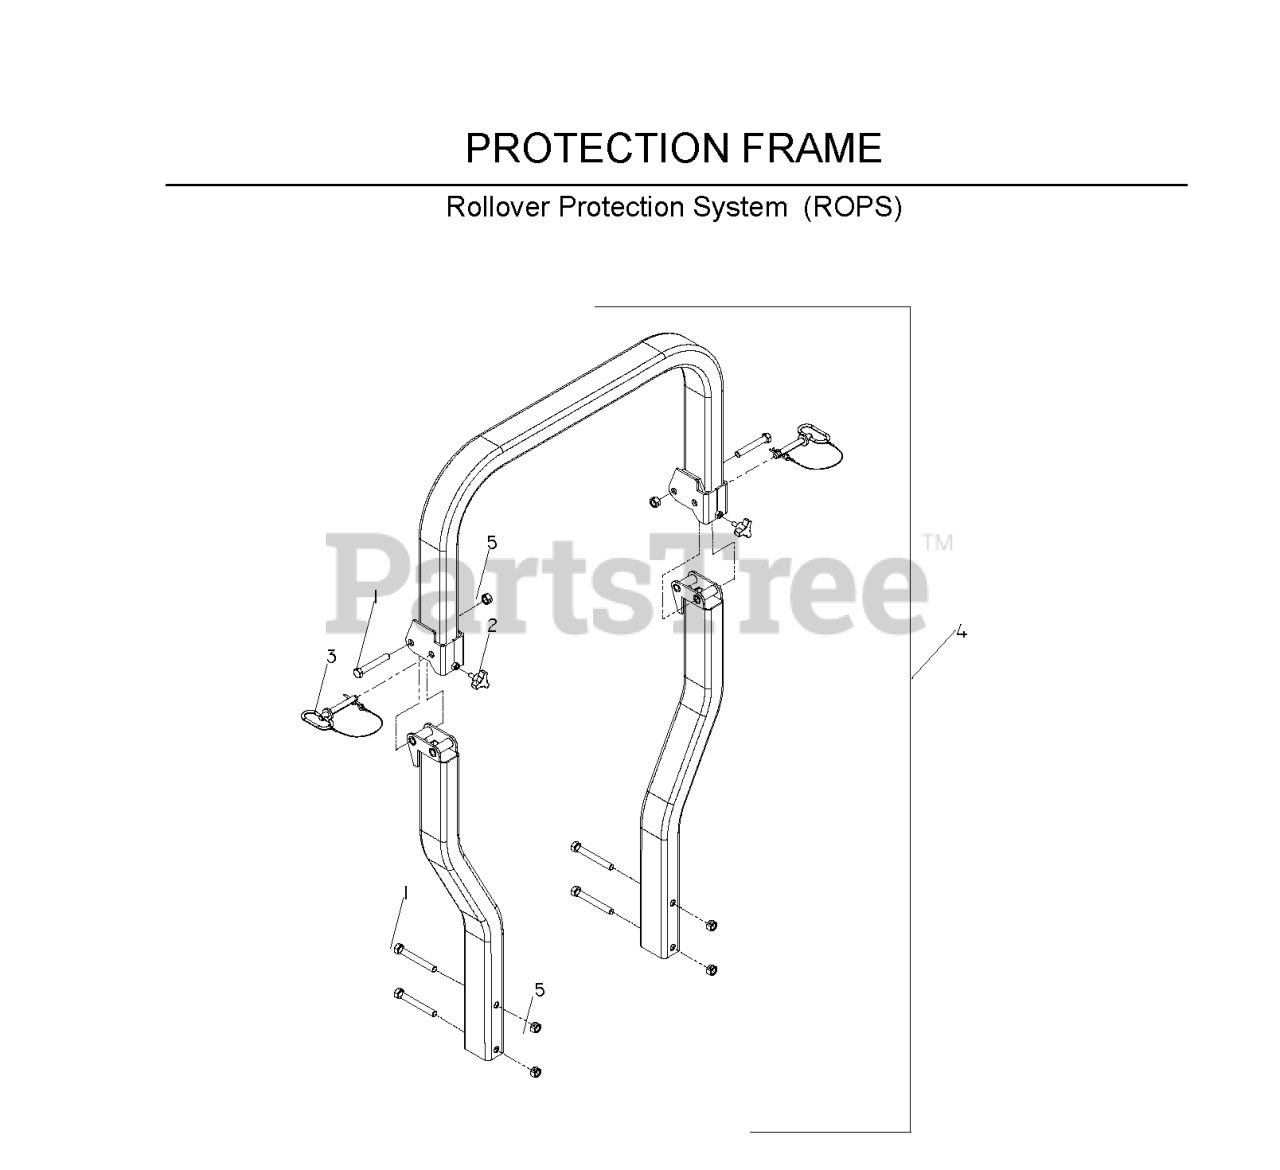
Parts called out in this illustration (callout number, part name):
1	HCS 1/2C X 3 1/4
2	KNOB W/STUD 3/8-16 X 1.5
3	PIN, 1/2" W/LANYARD
4	ROLL OVER PROTECTION SYSTEM
5	NUT 1/2-13 HEX CNTRLK GR 5 ZD
